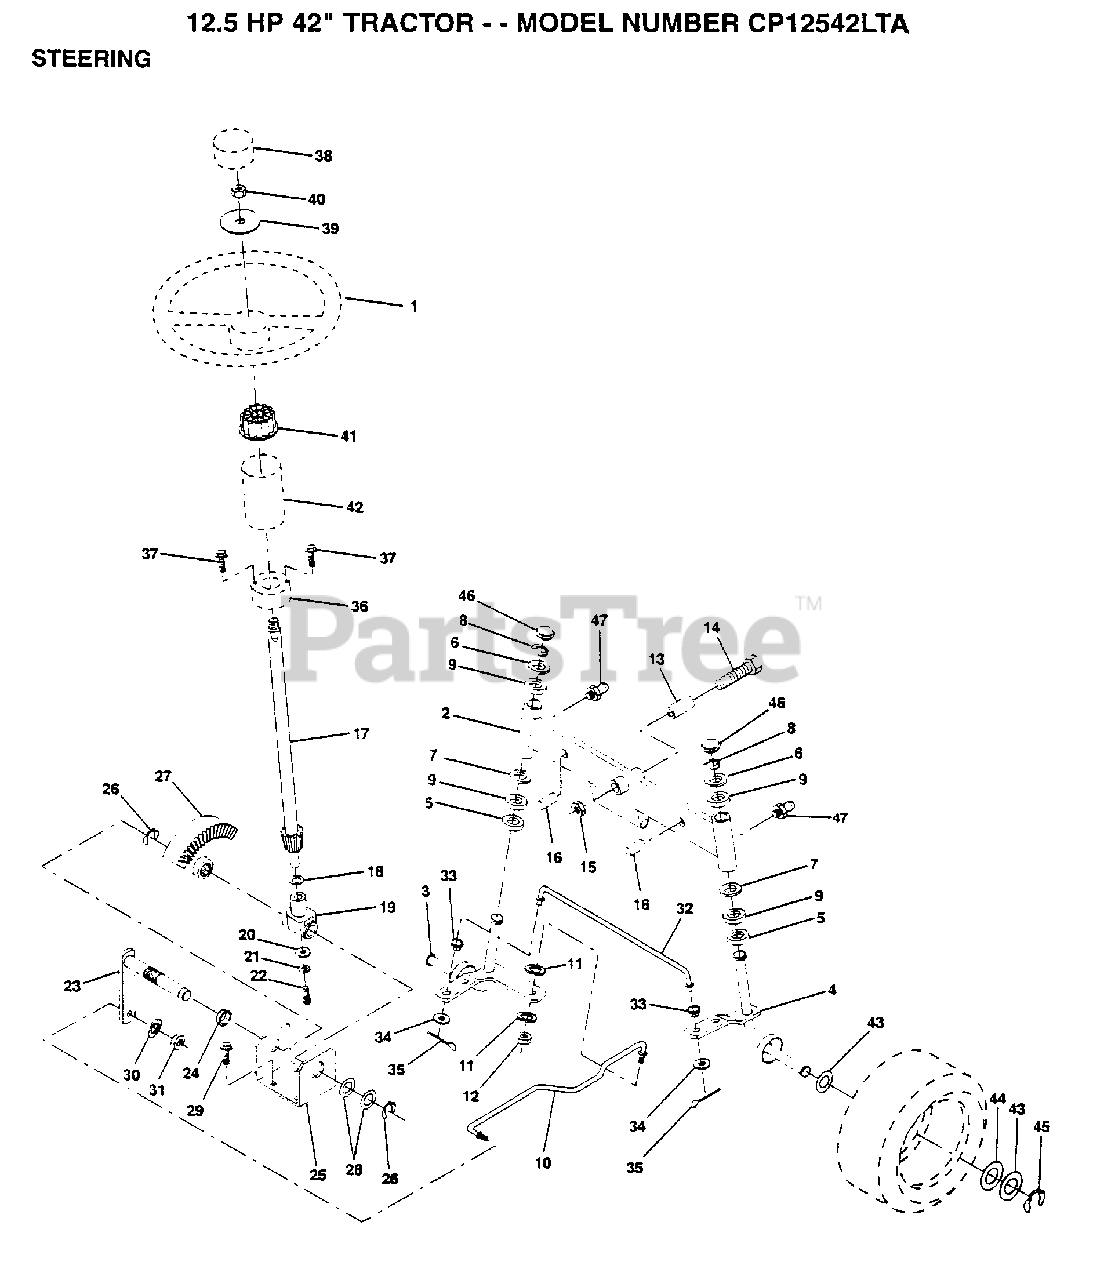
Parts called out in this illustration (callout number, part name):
2	AXLE ASM FRONT
3	SPINDLE LH
4	SPINDLE RH
5	WASHER .T
6	WASHER
7	WASHER
8	RING
9	COL. SRTG. BEAR.
11	LOCKWASHER
13	BEARING
14	BOLT HEX 5/8-11
15	"NUT-LOC,FLANGE LT"
16	AXLE PIN
17	SHAFT ASM
18	THRUST WASHER
19	SUPPORT.SHAFT
21	LOCKWASHER
22	"SCREW,SPECIAL"
24	NYLINER T
25	"BRKT,STEERING"
26	RING
27	GEAR SECTOR
28	WASHER .T
29	SCREW
30	LOCKWASHER
32	TIE ROD
33	BUSHING.DRAGLINK
34	WASHER
35	COTTER PIN
38	ST WHL INSERT CAP
39	WASHER T
40	GRIPCO NUT
41	ADAPTER-WHEEL LT
42	"TUBE, STR SHAFT"
43	WASHER
44	WASHER
45	RING
46	CAP
47	ZERK M
